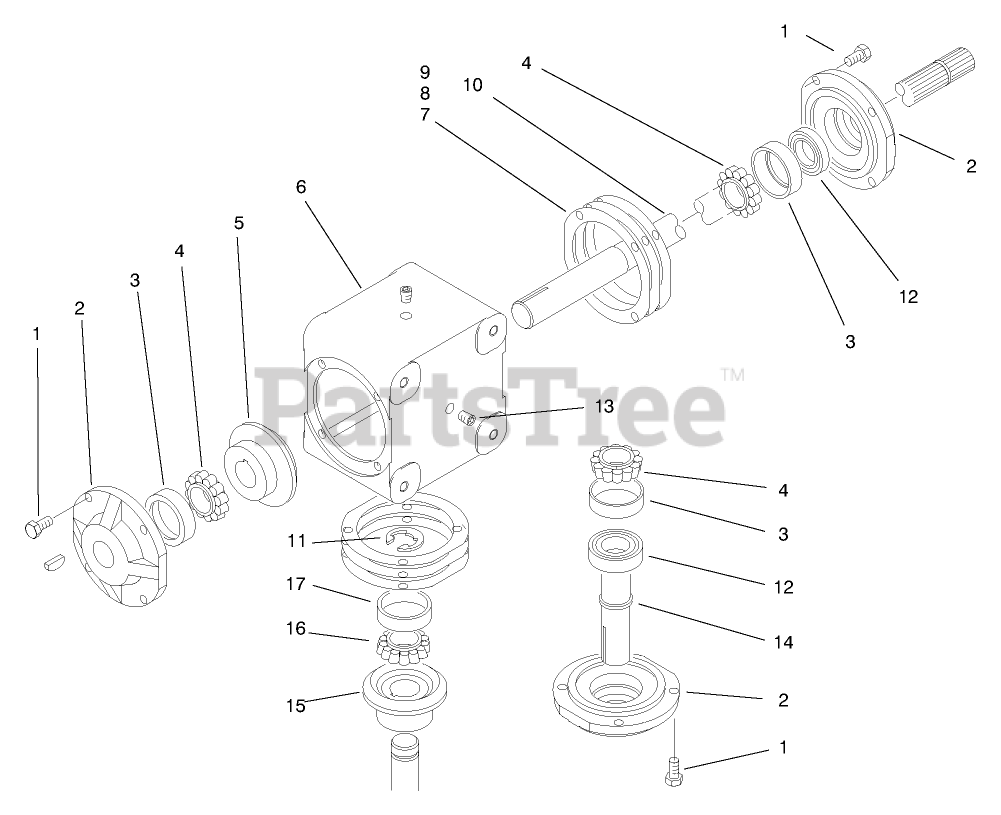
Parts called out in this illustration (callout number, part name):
1	SCREW
2	Cap
3	Cup
4	BEARING - CONE
5	GEAR LH
6	HOUSING
7	GASKET
8	GASKET
9	GASKET
10	SHAFT
11	Ring-Retaining
12	Seal
13	PLUG (OBS, C/R TO 281-10)
14	INPUT SHAFT
15	GEAR RH
16	Cone
17	Bearing Cup
